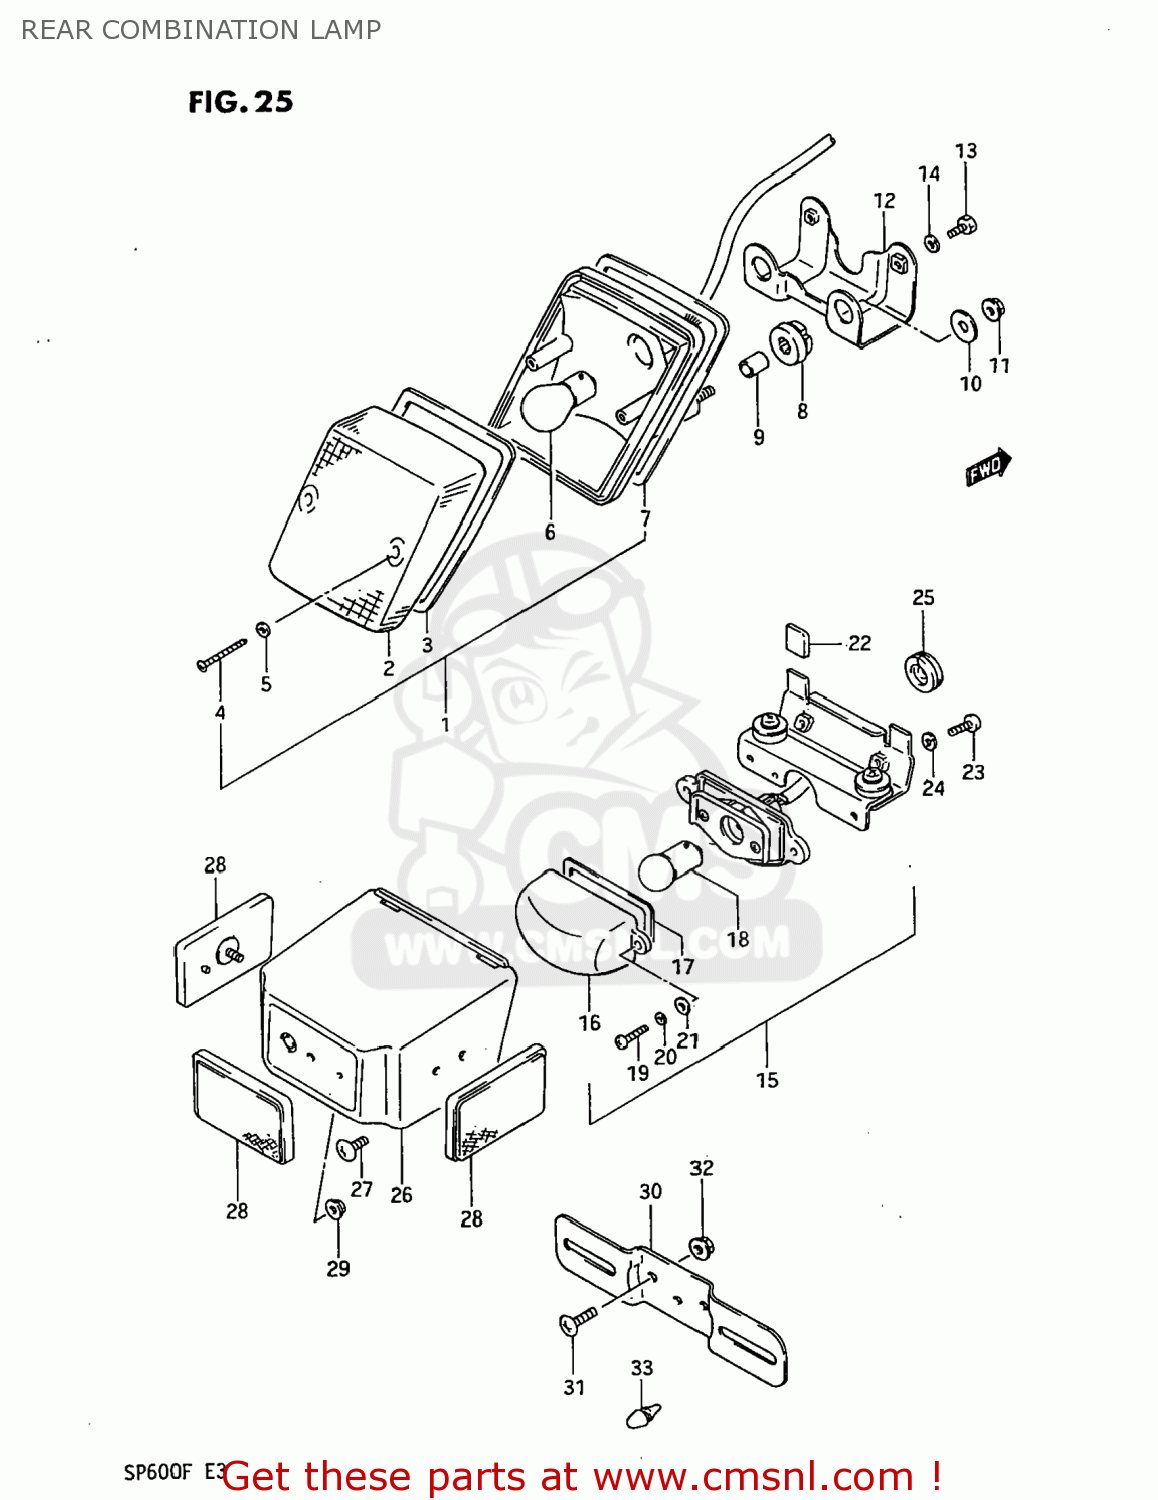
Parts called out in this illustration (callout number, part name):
1	LAMP ASSEMBLY,REAR COMBINATION
2	LENS,RR COMBI
3	GASKET,REAR COMBINATION LAMP
4	SCREW TAPP.
5	GASKET (NAS)
6	BULB(12V23/8W,TOKAI DENSO)
7	GASKET
8	CUSHION
9	SPACER (6.8X10X10)
10	WASHER (6.5X20X1.2)
11	NUT
12	BRACKET,REAR COMBINATION LAMP
13	BOLT
14	WASHER,LOCK
15	LAMP ASSEMBLY,LICENSE
16	LENS,LICENSE LAMP
17	GASKET,LICESE LAMP (NAS)
18	BULB
19	SCREW
20	LOCK WASHER
21	WASHER
22	CAP,LICENSE
23	SCREW
24	WASHER,LOCK
25	GROMMET
26	COVER,LICENSE LAMP
27	SCREW
28	REFLEX REFLECTOR,RR
29	NUT
30	BRACKET,REAR LICENSE
31	SCREW
32	NUT
33	CUSHION
